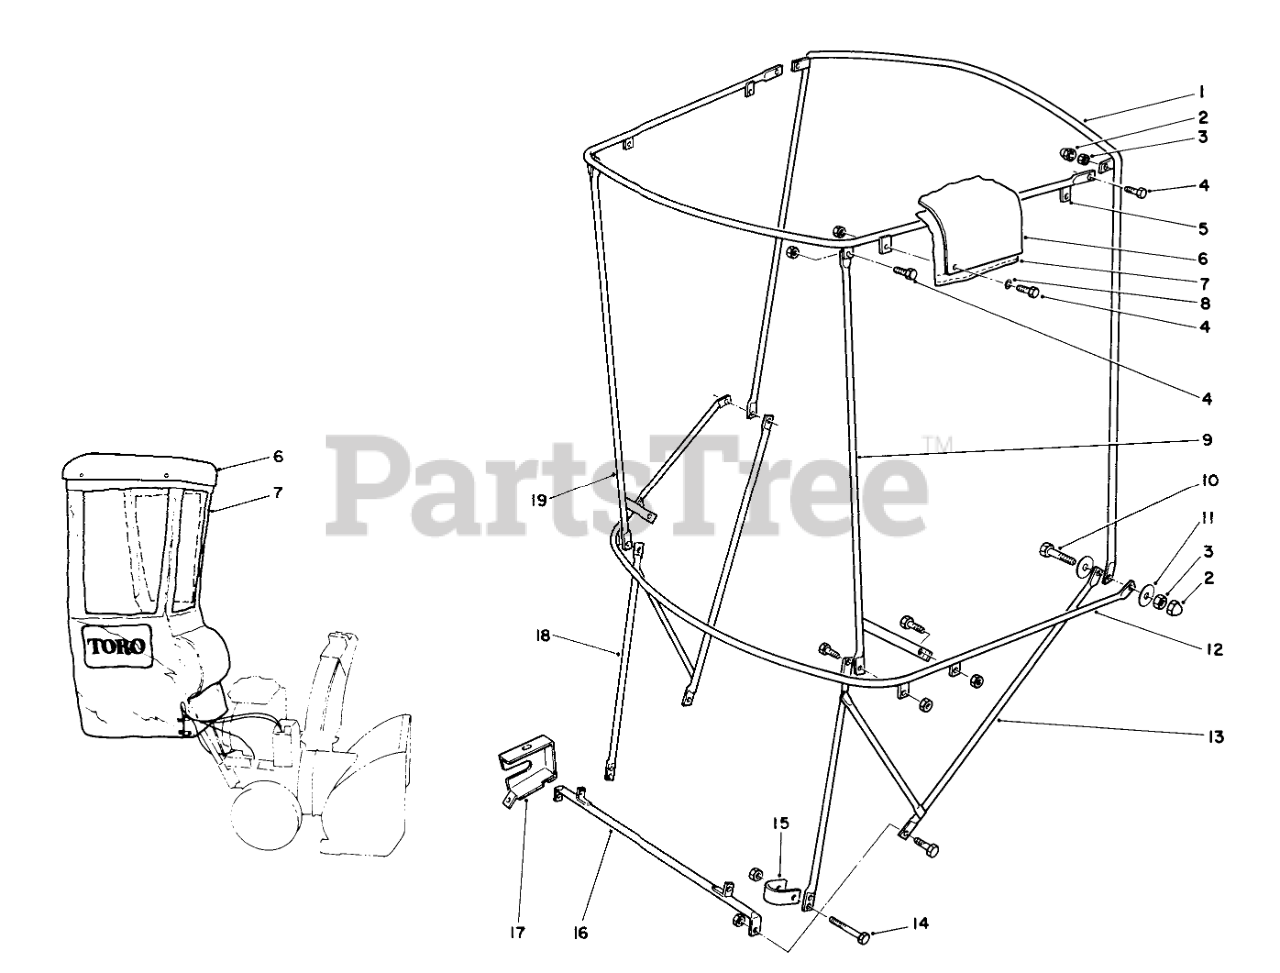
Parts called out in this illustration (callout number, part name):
1	VERTICAL BOW
2	CAPLUG
3	NUT-HEX, SIDE DEFORM
4	SCREW-HH
5	FRAME - TOP
6	Top-Plastic
7	Cover-Vinyl
8	WASHER-FLAT
9	CORNER POST - LH
10	SCREW-HH
11	WASHER-FLAT
12	HORIZONTAL BOW
13	Bracket-LH
14	SCREW-HH
15	CLAMP
16	Bracket-Base
17	COVER-LOCK, LEVER
18	BRACKET-RH
19	CORNER POST - RH
